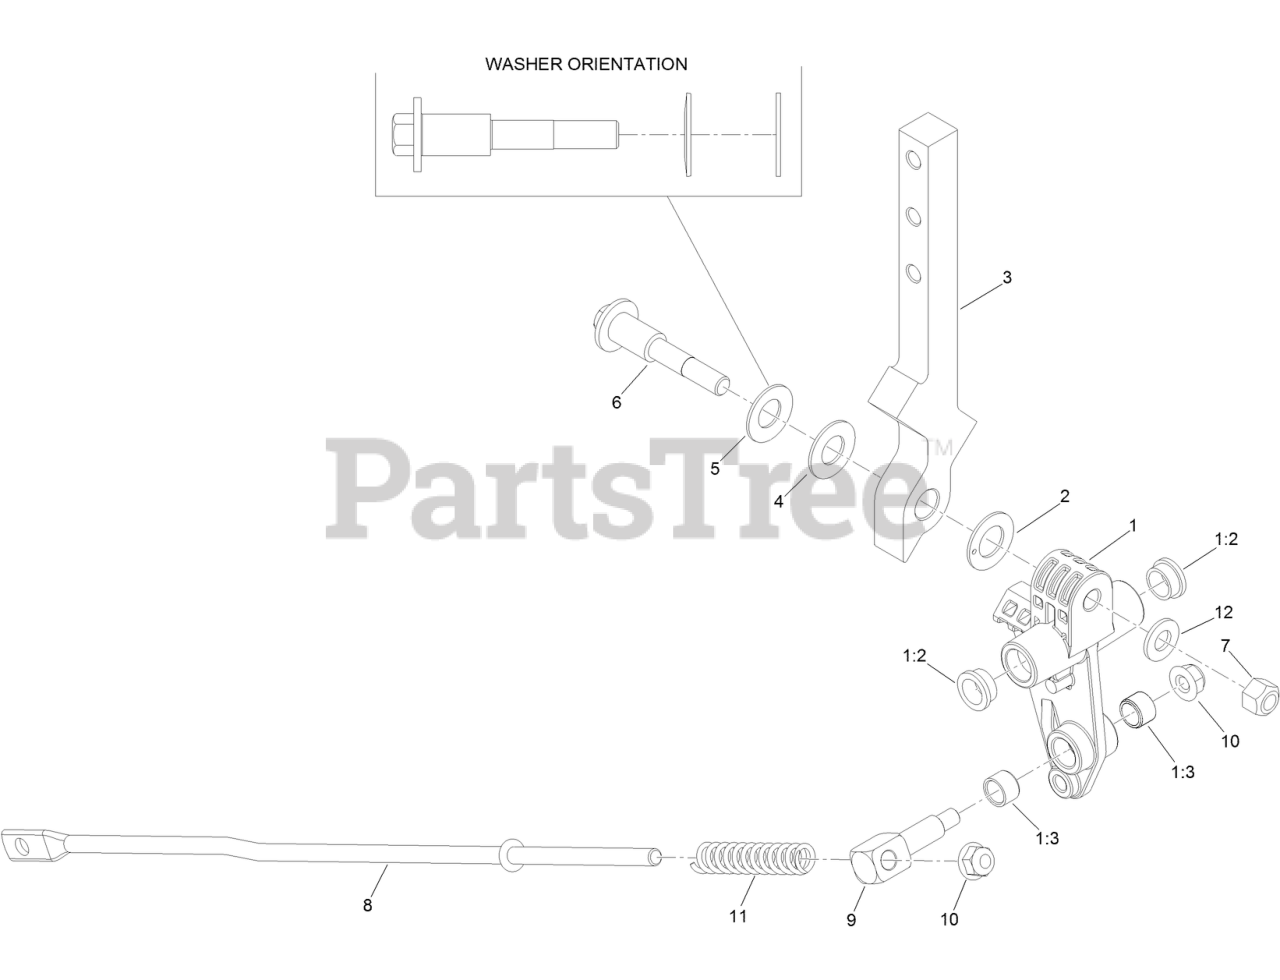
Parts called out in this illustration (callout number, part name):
1	CONTROL ARM ASM
1:2	BUSHING
1:3	BUSHING-SLEEVE
2	WASHER-FRICTION
3	ARM-CONTROL
4	WASHER
5	WASHER-BELLEVILLE
6	BOLT-PIVOT
7	NUT-LOCK, CONE
8	LINK-CONTROL
9	SWIVEL
10	NUT-HF, NI
11	SPRING-RETURN, NEUTRAL
12	WASHER-FLAT
